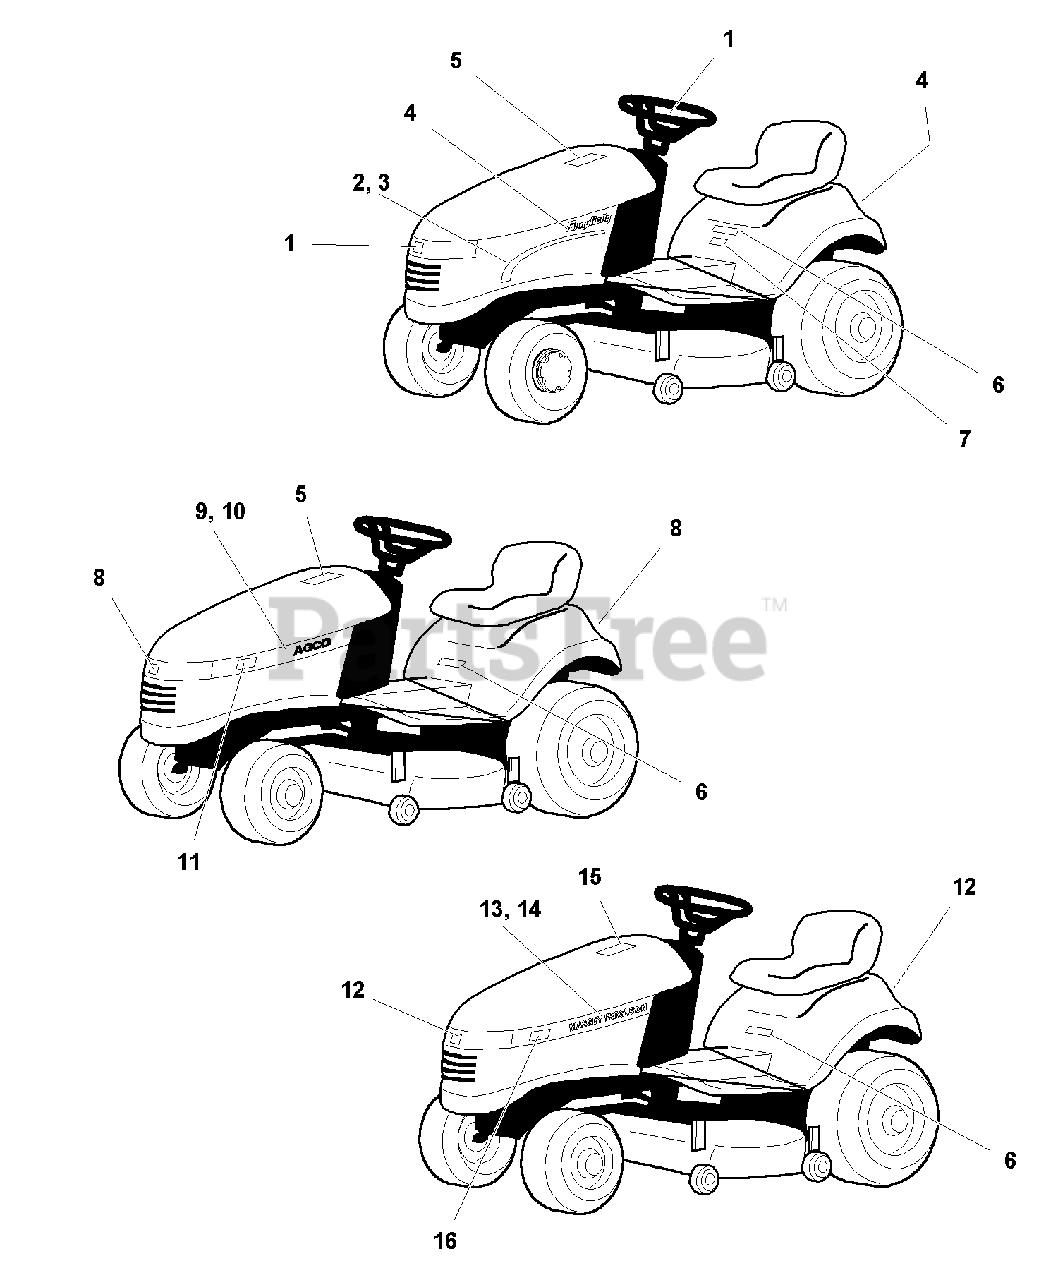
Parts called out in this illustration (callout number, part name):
1	DECAL, Simplicity Icon
2	DECAL, Simplicity, Stripe RH
3	DECAL, Simplicity, Stripe LH
4	DECAL, Simplicity
5	DECAL, Touch Up Paint
6	DECAL, Regent, Silver & Blue
7	DECAL, 17HP
8	DECAL, AGCO Logo
9	DECAL, AGCO, Hood Stripe RH
10	DECAL, AGCO, Hood Stripe LH
12	DECAL, Massey Ferguson
13	DECAL, Massey Ferguson, Hood Stripe RH
14	DECAL, Massey Ferguson, Hood Stripe LH
15	DECAL, Touch Up Paint, Massey Ferguson
16	DECAL, 2517
